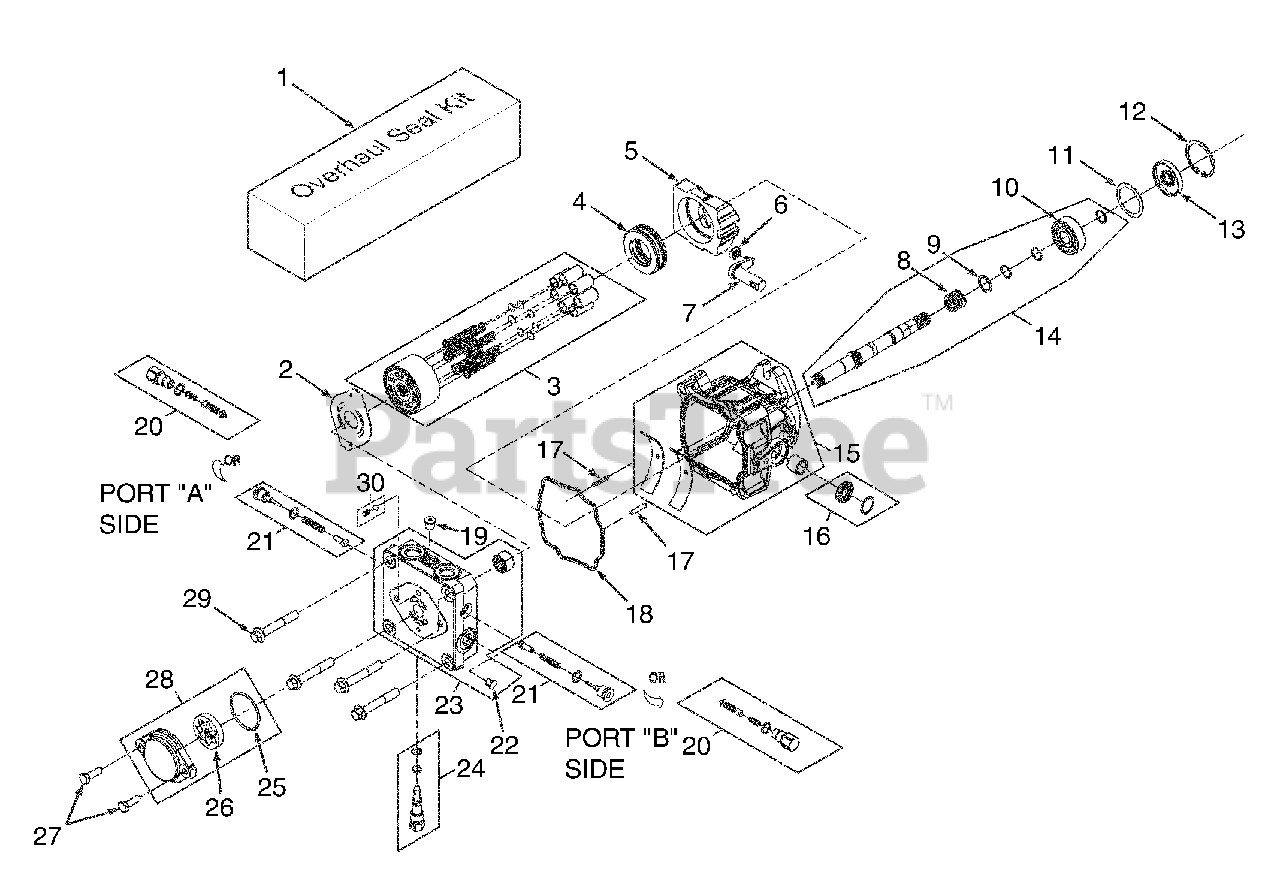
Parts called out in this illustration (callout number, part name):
1	Overhaul Seal Kit
2	Valve Plate
3	Cylinder Block Kit - 16cc
4	Thrust Ball Bearing Assembly
5	Variable Swashplate
6	Slot Guide
7	Trunnion Arm
8	Block Spring
9	Block Thrust Washer
10	Shaft Ball Bearing
12	Retaining Ring
14	Kit, Pump Shaft
15	Housing Kit
16	Trunnion Seal Kit
18	O-Ring
19	Straight Thread Plug
20	Shock Valve Kit (.031 Orifice)
21	Shock Valve Kit (.024 Orifice)
22	Straight Thread Plug
23	End Cap Kit
24	Bypass Valve Kit
26	Gerotor Assembly (.19 cu.in./rev.)
27	Socket Head Cap Screw (M8 x 1.25-25mm)
28	Charge Pump Kit (.19 STD. Splined)
29	Hex Screw, Flanged Head (M10 x 1.50-65mm)
30	Charge Relief Kit
